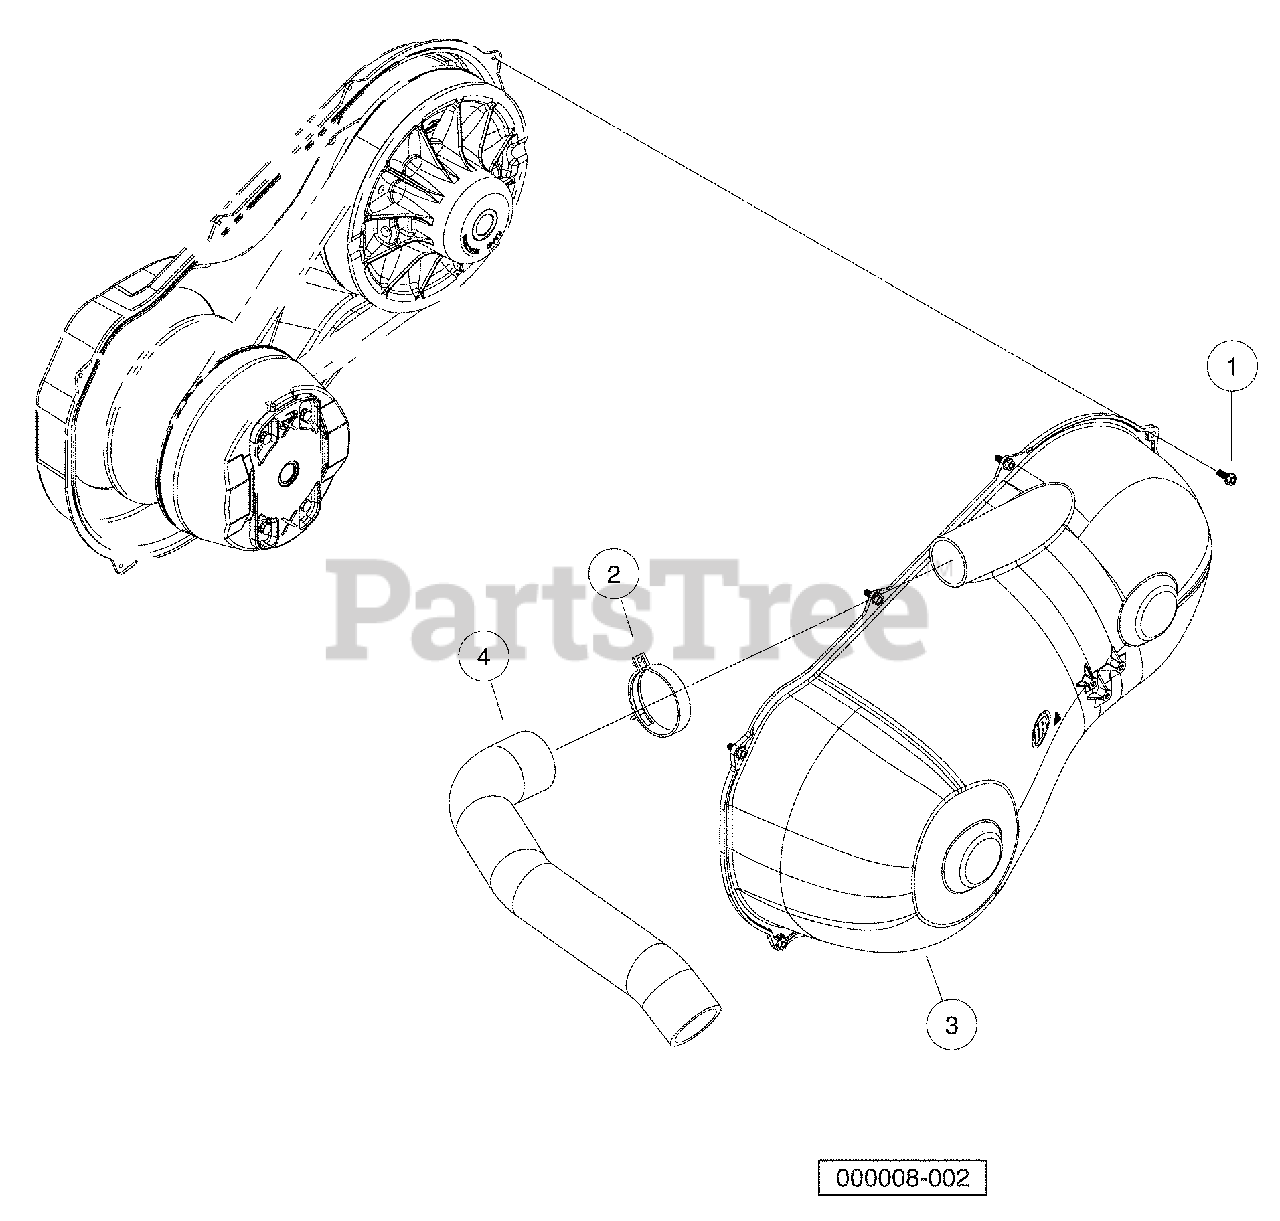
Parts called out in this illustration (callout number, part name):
1	Screw, M6 X 16 Tt Hx Fl Hd
2	Clamp, Hose, Ctb 64mm
3	ERROR! No Husqvarna Part Number for Club Car part number 102628301Cover, Cvt, Open
4	Hose, Outlet, Cvt
